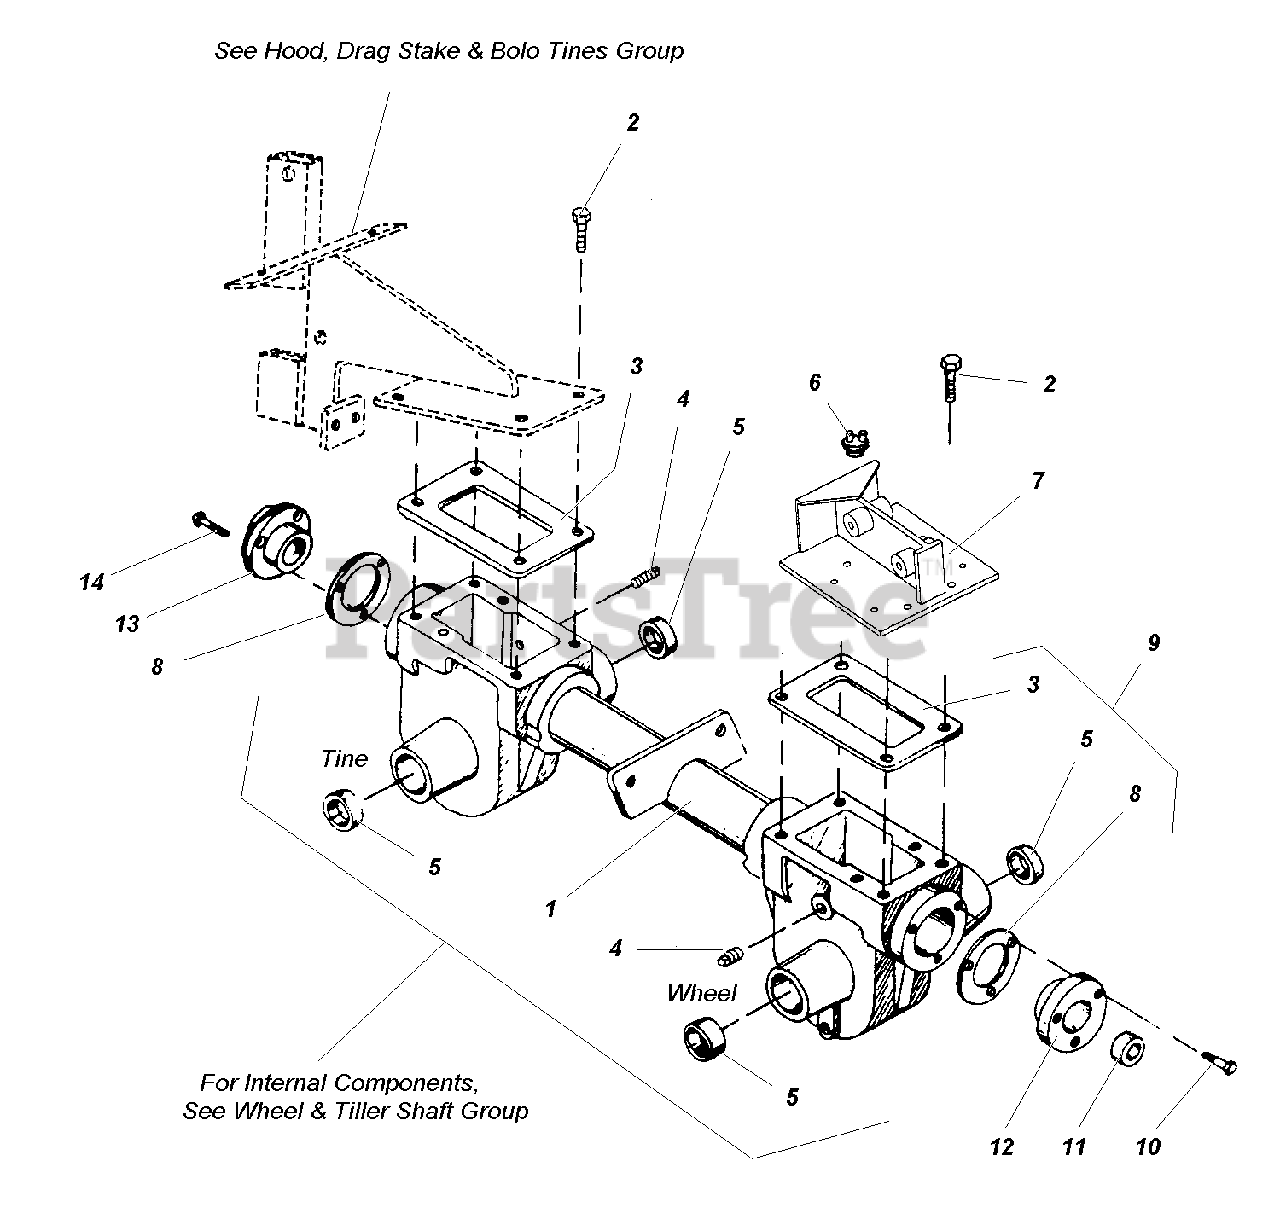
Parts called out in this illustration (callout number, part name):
1	TRANSMISSION ASSEMBLY
2	CAPSCREW, Hex Flagne Head, 5/16"- 18 x 3/4"
3	GASKET, Housing & Transmission Cover
4	PLUG, Pipe Socket Head 1/4"- 18, Oil Check
5	SEAL, Housing 1506
6	PLUG, Oil Fill
7	COVER, Transmission Wheel Housing
8	GASKET, Bearing Cap Front, Rear
9	GASKET KIT, Oil Seal (Includes Ref. Nos. 3, 5, and 8)
10	CAPSCREW, Hex Flange Head, 1/4"- 20 x 3/4"
11	SEAL, Oil Drive Shaft
12	CAP, Front Bearing
13	CAP, Rear Bearing
14	CAPSCREW, Hex Flange Head, 1/4"- 20 x 7/8"
